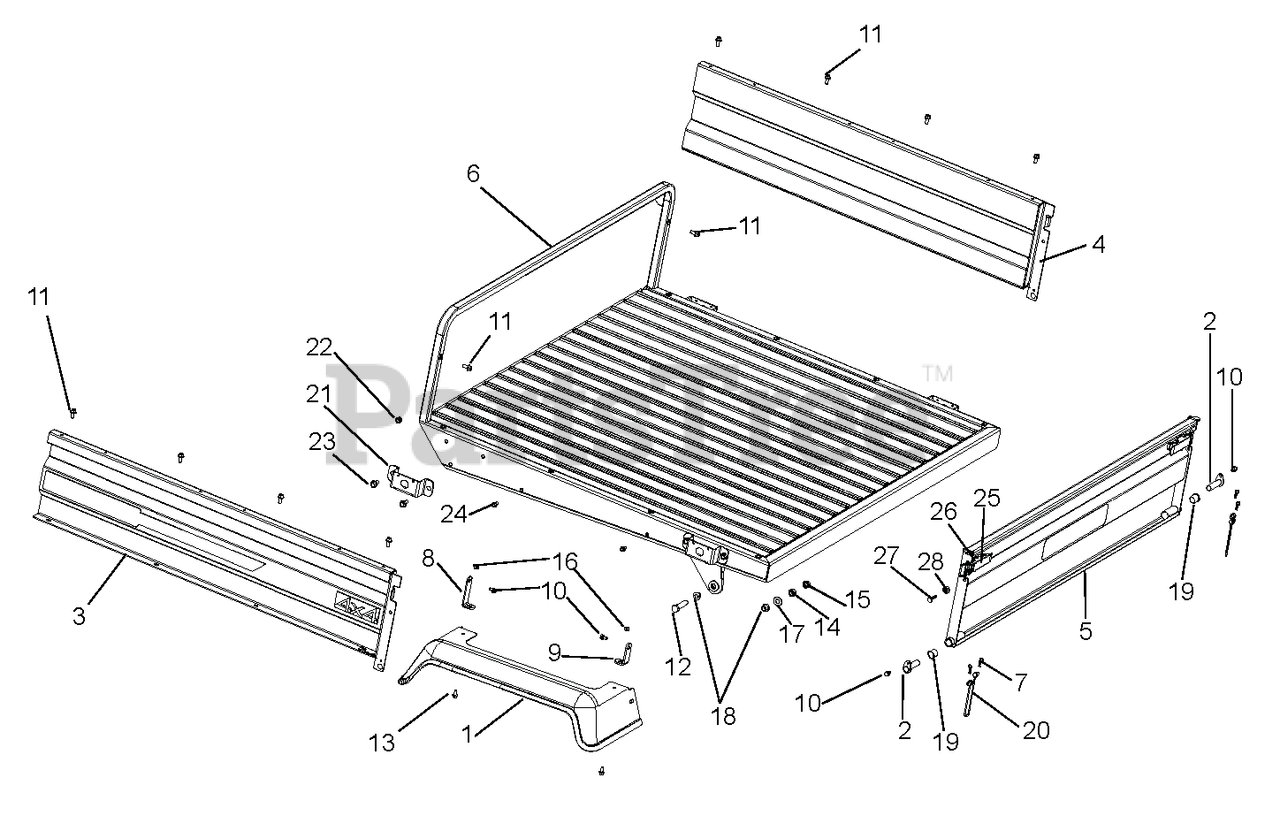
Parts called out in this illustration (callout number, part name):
1	FENDER, REAR UNIVERSAL
2	WELDMENT, TAILGATE PIVOT
3	KIT,LH ARIENS BED SIDE W/DECAL
4	KIT,RH ARIENS BED SIDE W/DECAL
5	KIT,ARIENS TAILGATE W/DECALS
6	ASM, BED BASE
7	PIN-HAIR INT .08X.18X1.18 YWZC
8	BRACKET, FENDER MOUNT FRONT
9	BRACKET, FENDER MOUNT REAR
10	SCREW HEX SELF-TAP 1/4-20X 1/2
11	BLT-SERHFWH .312-18X.75 YWZC
12	HFS 1/2-13X2 1/4 GR5 PLT
13	BLT-SCRHFWH .25-20X.62 YWZC
14	@NUT-LK-CTR .50-13 YWZC
15	NUT-JAM .50-13 YWZC
16	@NUT-LK-TOP-FLG .25-20 YWZC
17	@WSHR-FL-STL.531X1.06X.095YWZC
18	BUSHING 1/2IDX5/8ODX1/2 FLANGE
19	BSHG FLG .63IDX.75ODX1.50L
20	CABLE, TAILGATE,11.25"
21	BRACKET,TREKER,STAKE POCKET
22	@NUT-LK-NYL .38-16 YWZC
23	BLT-SERHFWH .38-16X.75 YWZC
24	BLT-SCRHFWH .25-20X.62 YWZC
25	LATCH, TAILGATE
26	SPACER, LATCH
27	BLT-RDHDSQNK 10-24X.75 G5 Y
28	@NUT-LK-NYL 10-24 W/INSRT YWZC
